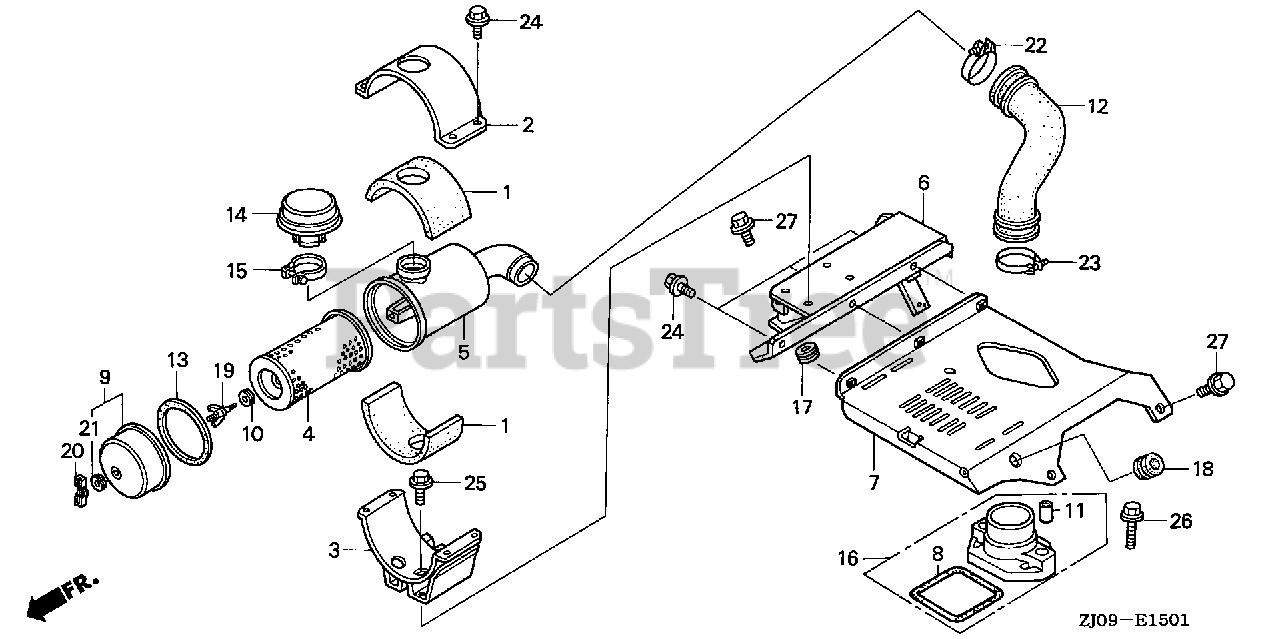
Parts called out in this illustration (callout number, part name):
1	RUBBER, AIR CLEANER HOLDER (UPPER)
2	HOLDER, AIR CLEANER (UPPER)
3	HOLDER, AIR CLEANER (LOWER)
4	ELEMENT, AIR CLEANER
5	HOUSING, AIR CLEANER (SNORKEL)
6	STAY A, AIR CLEANER (SNORKEL)
7	STAY B, AIR CLEANER (SNORKEL)
8	SEAL, AIR CLEANER HOUSING
9	COVER, AIR CLEANER
10	GROMMET, AIR CLEANER
11	COLLAR A, AIR CLEANER
12	TUBE, AIR CLEANER CONNECTING
13	SEAL, AIR CLEANER
14	CAP, IN.
15	CLAMP ASSY.
16	JOINT ASSY., CONNECTING TUBE (B)
17	GROMMET, RESERVE TANK
18	GROMMET
19	BOLT, AIR CLEANER
20	WINGNUT (6MM)
21	WASHER, AIR CLEANER
22	BAND, AIR CLEANER CONNECTING TUBE (50)
23	BAND, AIR CLEANER CONNECTING TUBE (58)
24	BOLT, FLANGE (6X12)
25	BOLT, FLANGE (6X16)
26	BOLT, FLANGE (6X28)
27	BOLT, FLANGE (8X20)
